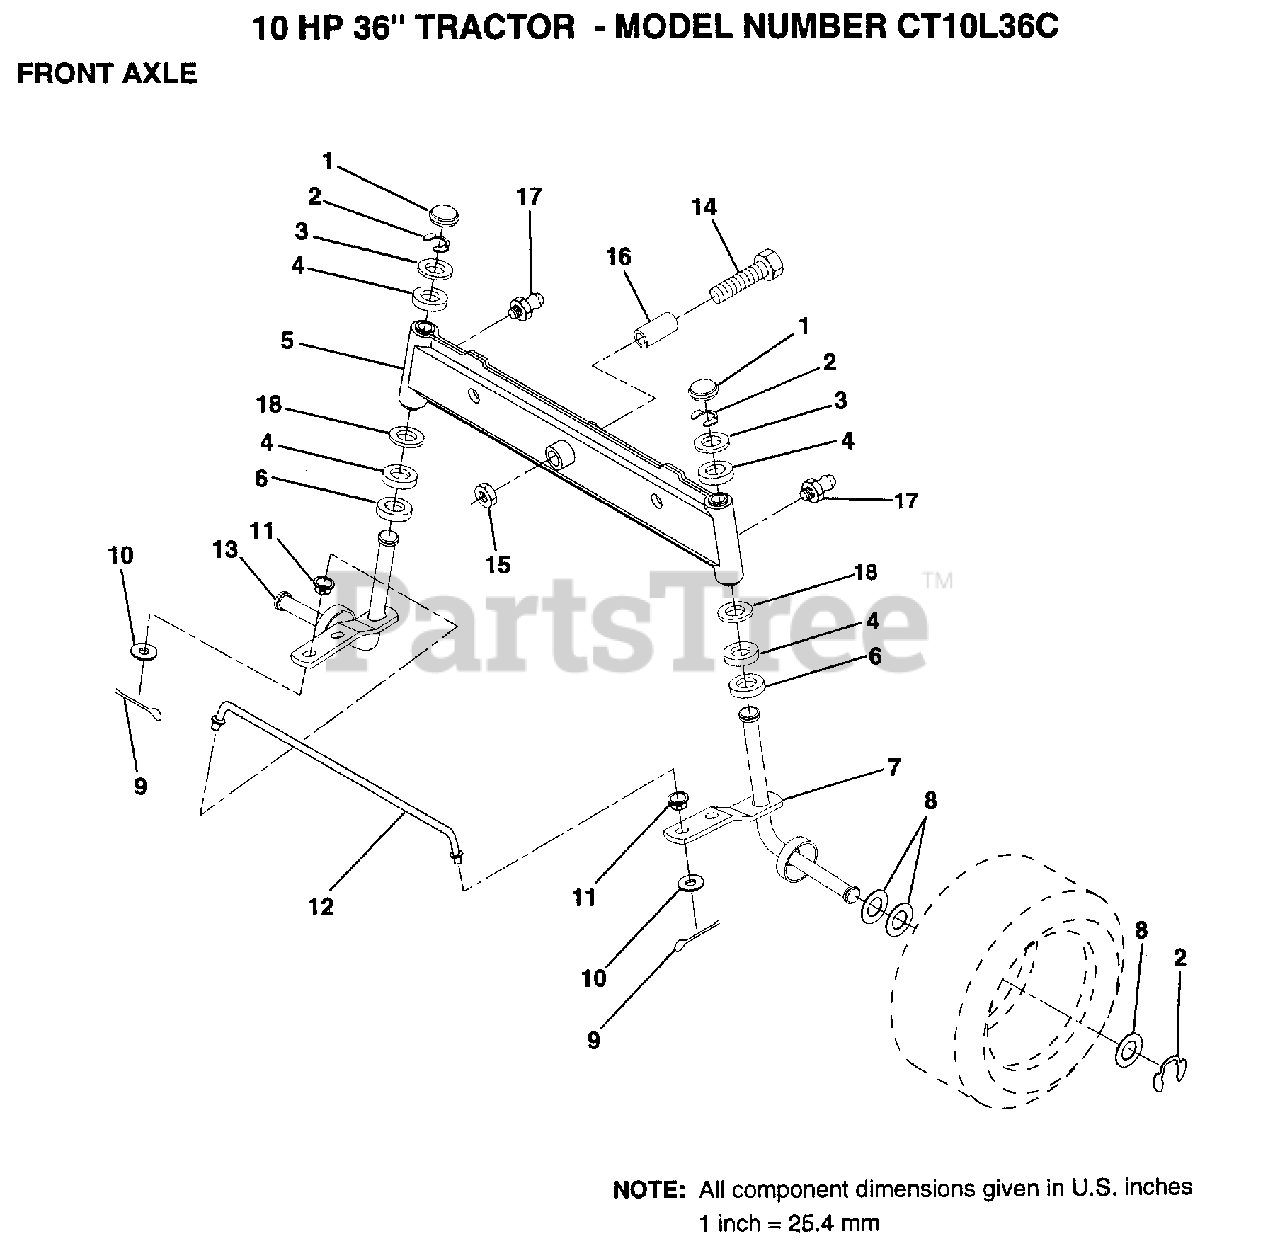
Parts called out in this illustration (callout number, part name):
1	CAP
2	RING
3	WASHER
4	COL. SRTG. BEAR.
5	AXLE ASM FRONT
6	WASHER .T
7	SPINDLE ASM RH
8	WASHER
9	COTTER PIN
10	WASHER
11	BUSHING.DRAGLINK
12	TIE ROD
13	SPINDLE ASM LH
14	BOLT HEX 5/8-11
15	"NUT-LOC,FLANGE LT"
16	BEARING
17	ZERK M
18	WASHER
